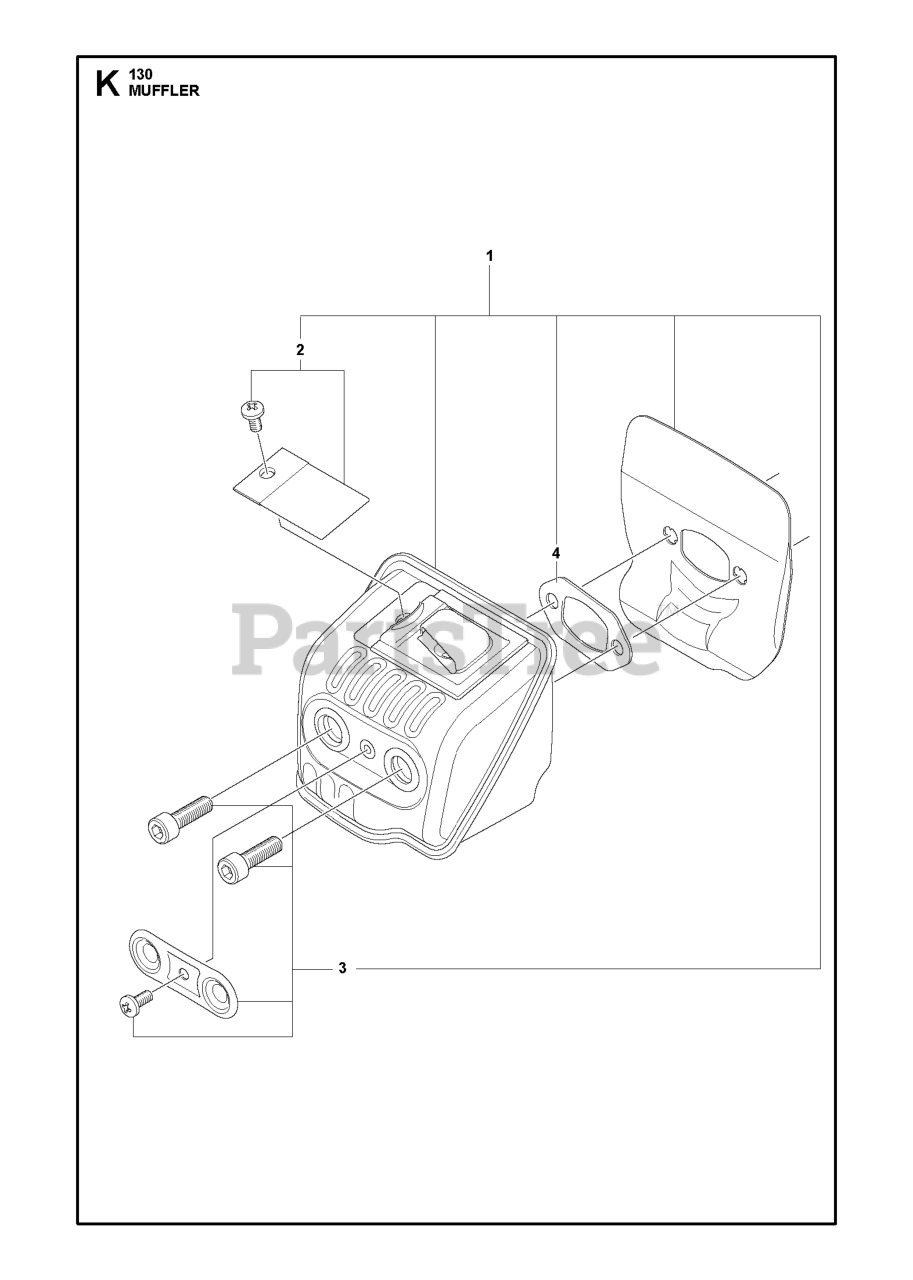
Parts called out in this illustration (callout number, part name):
1	MUFFLER ASSY 38CC
2	SERVICE KIT SPARK ARRESTOR
3	SERVICE KIT MUFFLER
4	GASKET MUFFLER 38CC
